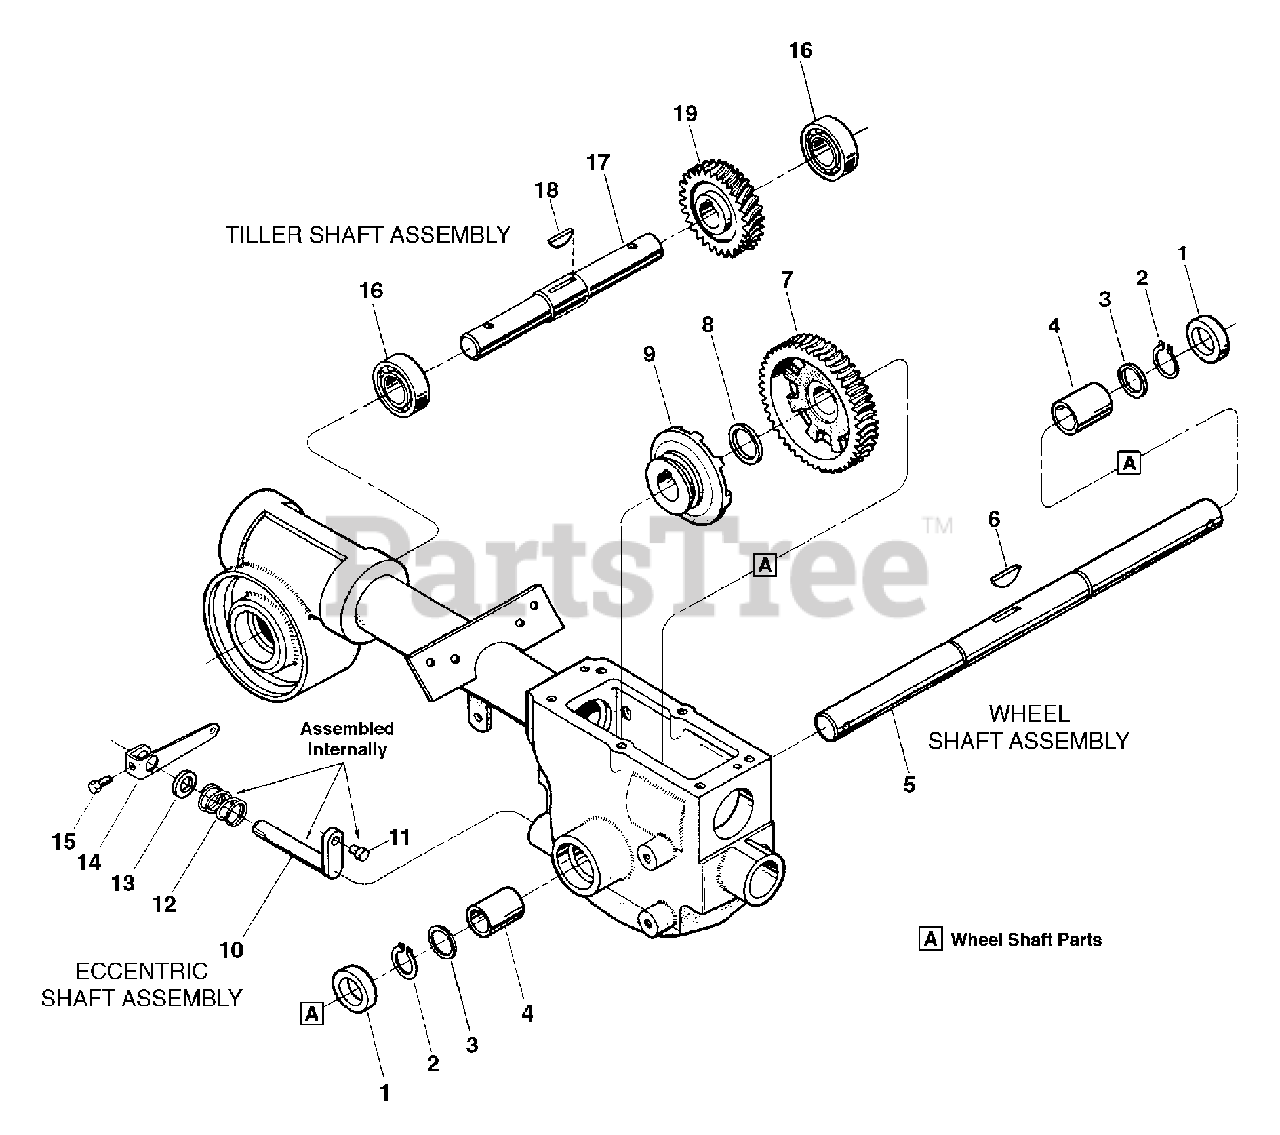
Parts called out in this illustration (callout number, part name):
1	Oil seal, left and right sides
2	Ring, retaining, heavy duty, external
3	Shim, 1-1/64 I.D., .062" thick
4	Bushing
5	Wheel shaft (axle)
6	Key, Hi-Pro, 1/4 x 1- 5/16
7	Gear, worm drive, cast iron
8	Shim, 1.016 I.D.x 1.468 O.D. x .062 thick
9	Clutch, wheel drive, cast iron
10	Eccentric shaft
11	Pin, eccentric shaft
12	Spring
13	Oil seal, eccentric shaft
14	Lever, eccentric shaft
15	Screw, hex hd., 1/4-20 x 1/2
16	Ball bearing, tiller shaft
17	Tiller shaft,
18	Key, woodruff, 1/4 x 1- 1/4
19	Worm gear, bronze, tiller drive
